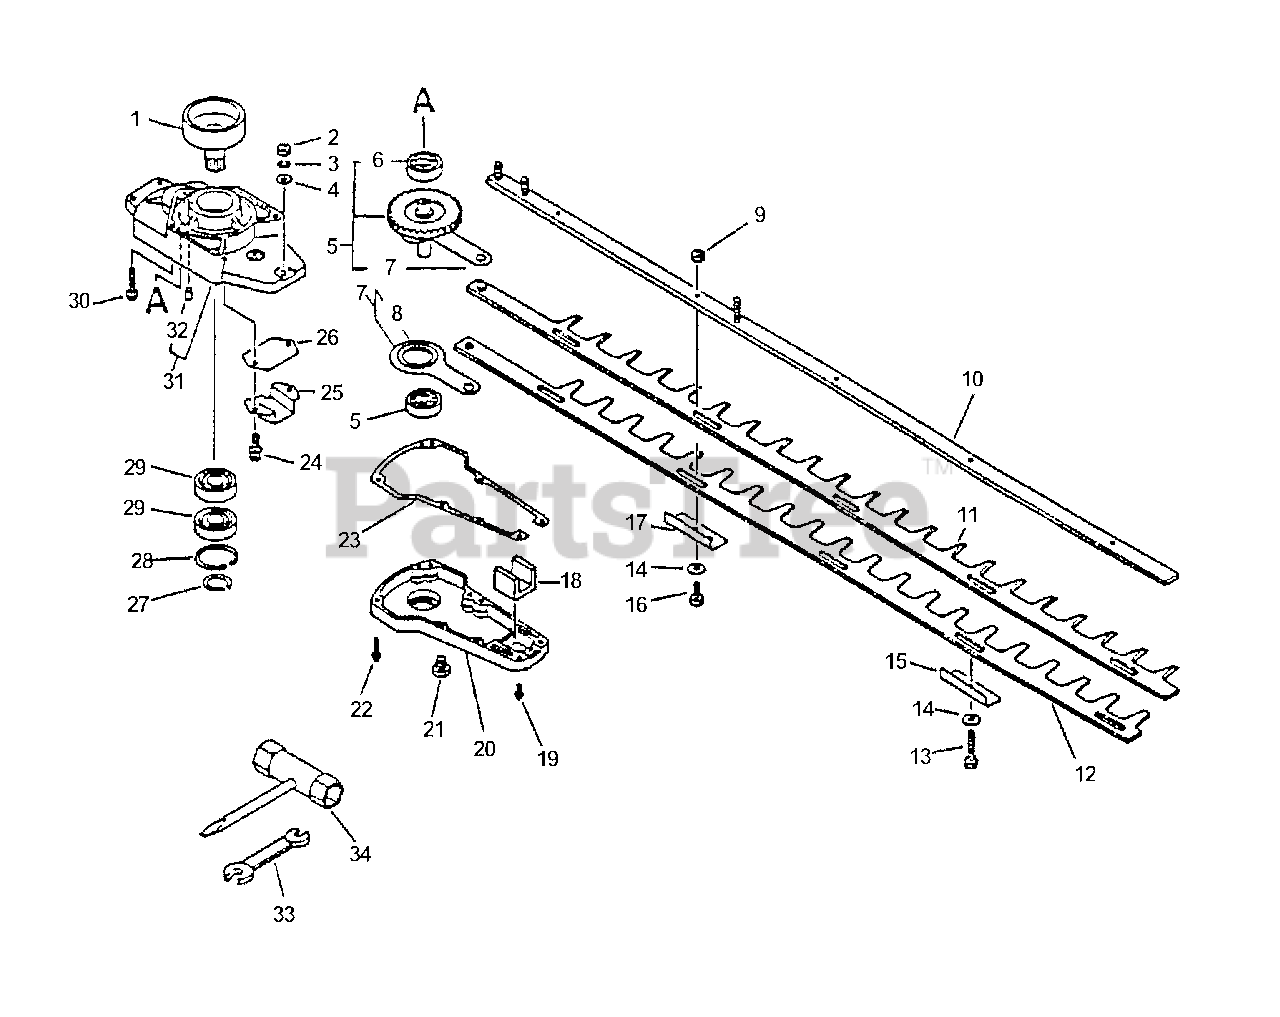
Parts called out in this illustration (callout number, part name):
1	DRUM, CLUTCH
2	LOCKNUT - 6
3	LOCKWASHER - 6
4	WASHER - 6
5	GEAR ASSY
6	BEARING, BALL - 6200
7	CONNECTING ROD ASSY
8	BEARING, NEEDLE
10	SUPPORT, BLADE
11	BLADE - UPPER
12	BLADE - LOWER
15	INSULATOR
16	BOLT
17	INSULATOR
18	SEAL, FELT
19	SCREW - 4X16
20	LID, GEAR CASE
21	BOLT - 8X8
22	SCREW - 4X22
23	GASKET, GEAR CASE
24	SCREW - 5X14
25	GUIDE
26	PLATE, GUIDE
27	RING, RETAINING - 16
28	RING, RETAINING - 35
29	BEARING, BALL - 6003
30	SCREW - 5X30
31	CASE, GEAR
32	PIN - LOCATING
33	SPANNER - 8X10mm
34	T-WRENCH - 14X19mm
